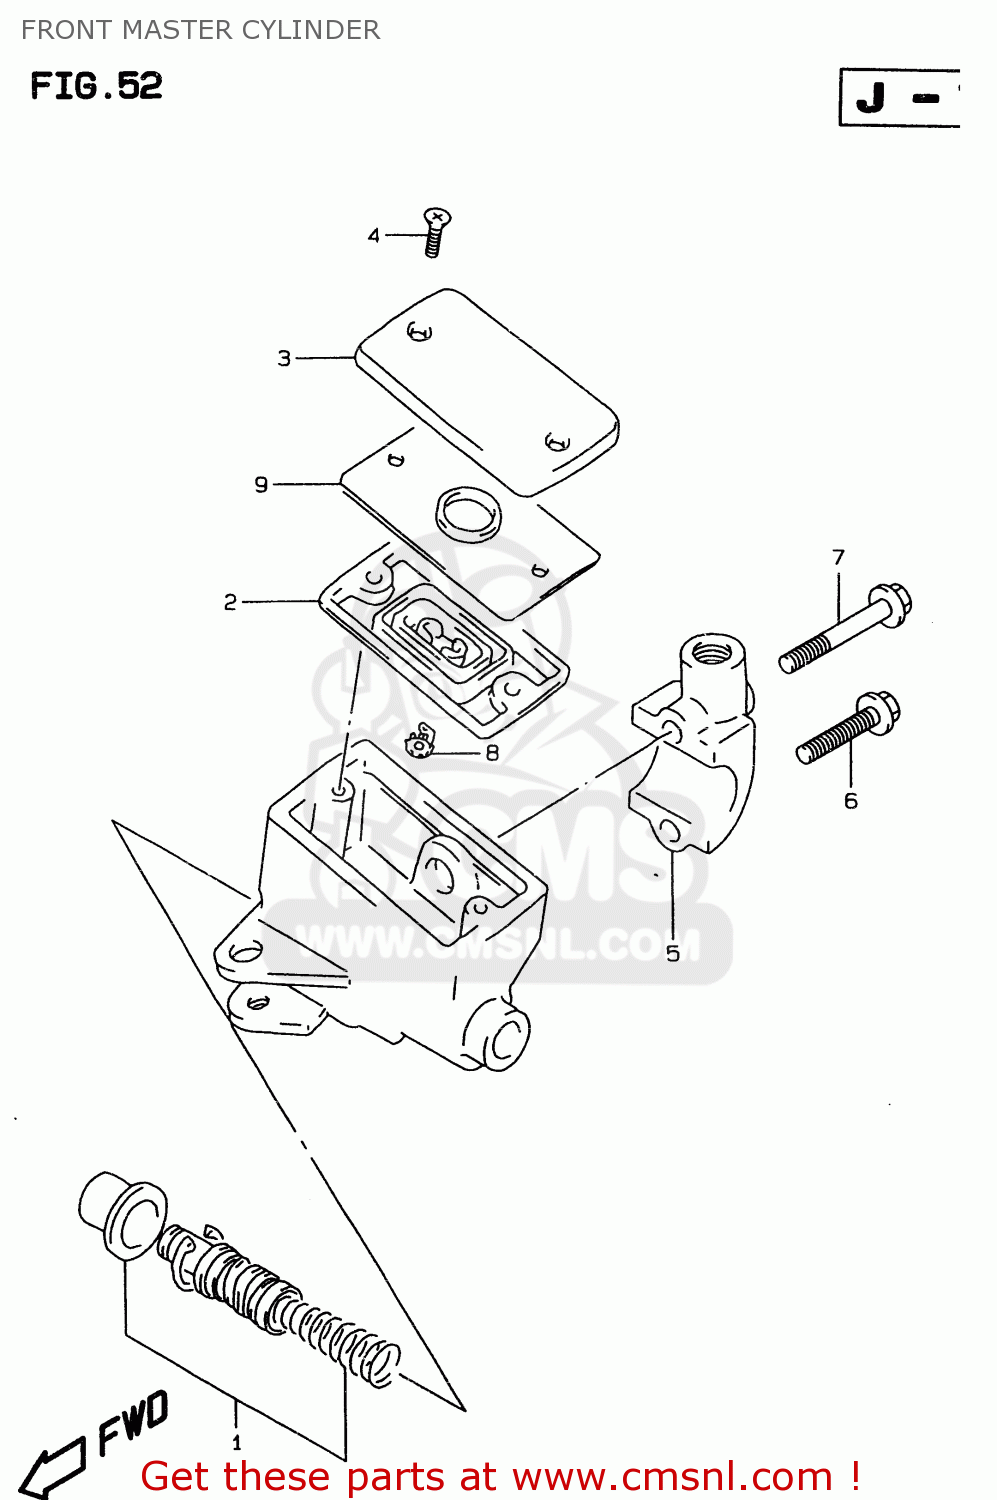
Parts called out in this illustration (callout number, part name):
1	PISTON & CUP SET
2	3
3	CAP
4	SCREW
5	HOLDER
6	BOLT(6X25)
7	BOLT(6X38)
8	PROTECTOR
9	PLATE,DIAPHRAGM
